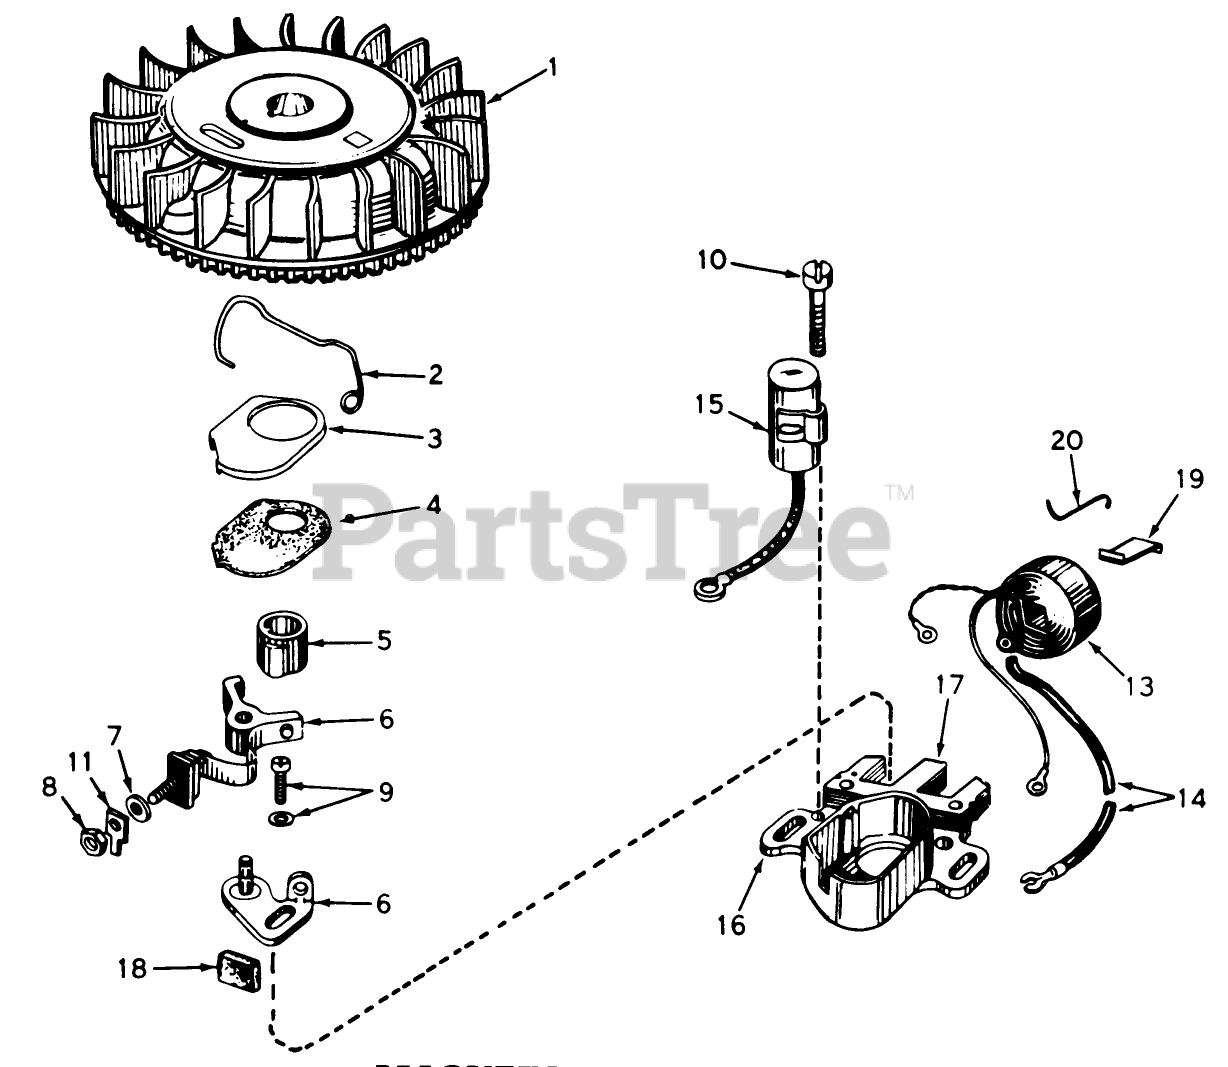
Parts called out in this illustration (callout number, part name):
1	Flywheel (Incl. Ref. #3 4)
2	Spring Breaker Box
3	Cover-Dust
4	Gasket, Dust Cover
5	Cam, Breaker
6	Breaker Assy.
7	Washer
8	DECAL
9	Breaker Screw
10	Condenser Screw
11	Terminal, Ground
13	Coil Assy. (Incl. No. 12)
14	Wire, Lead
15	Condenser
16	Core Plate
17	Stator Assy. (Incl. Ref. #2 thru 11, 13, 14, 16, 17 19)
18	Felt,Cam Wiper
19	Spring Coil Wedge
20	Clip, Coil
